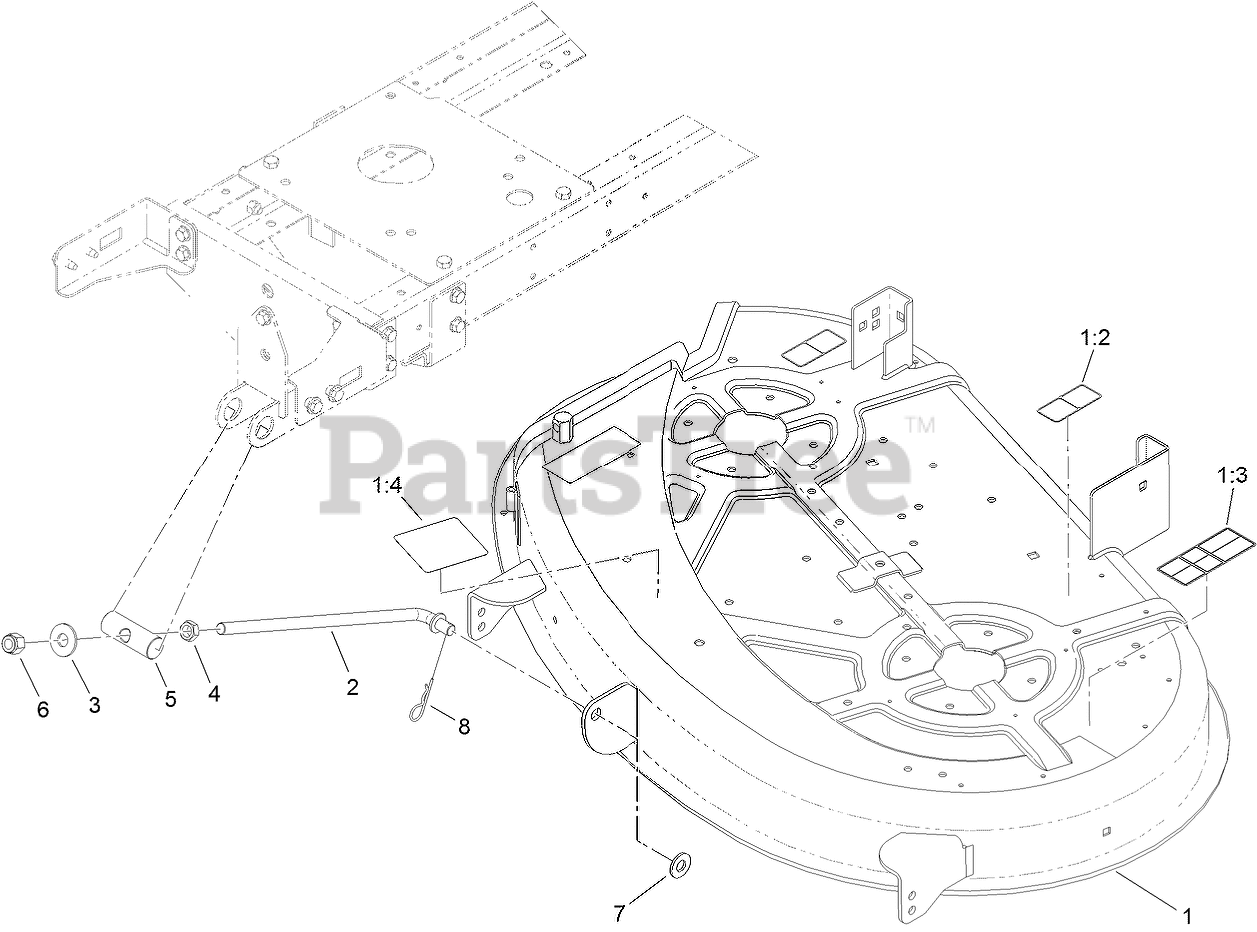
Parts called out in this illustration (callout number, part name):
1	38 INCH DECK ASM
1:2	DECAL-WARNING
1:3	DECAL-WARNING
1:4	DECAL-GUIDE, BELT
2	ROD-PIVOT
3	WASHER-FLAT
4	NUT-JAM
5	PIN-PIVOT
6	NUT-HEX
7	WASHER-THRUST
8	PIN-HAIR
